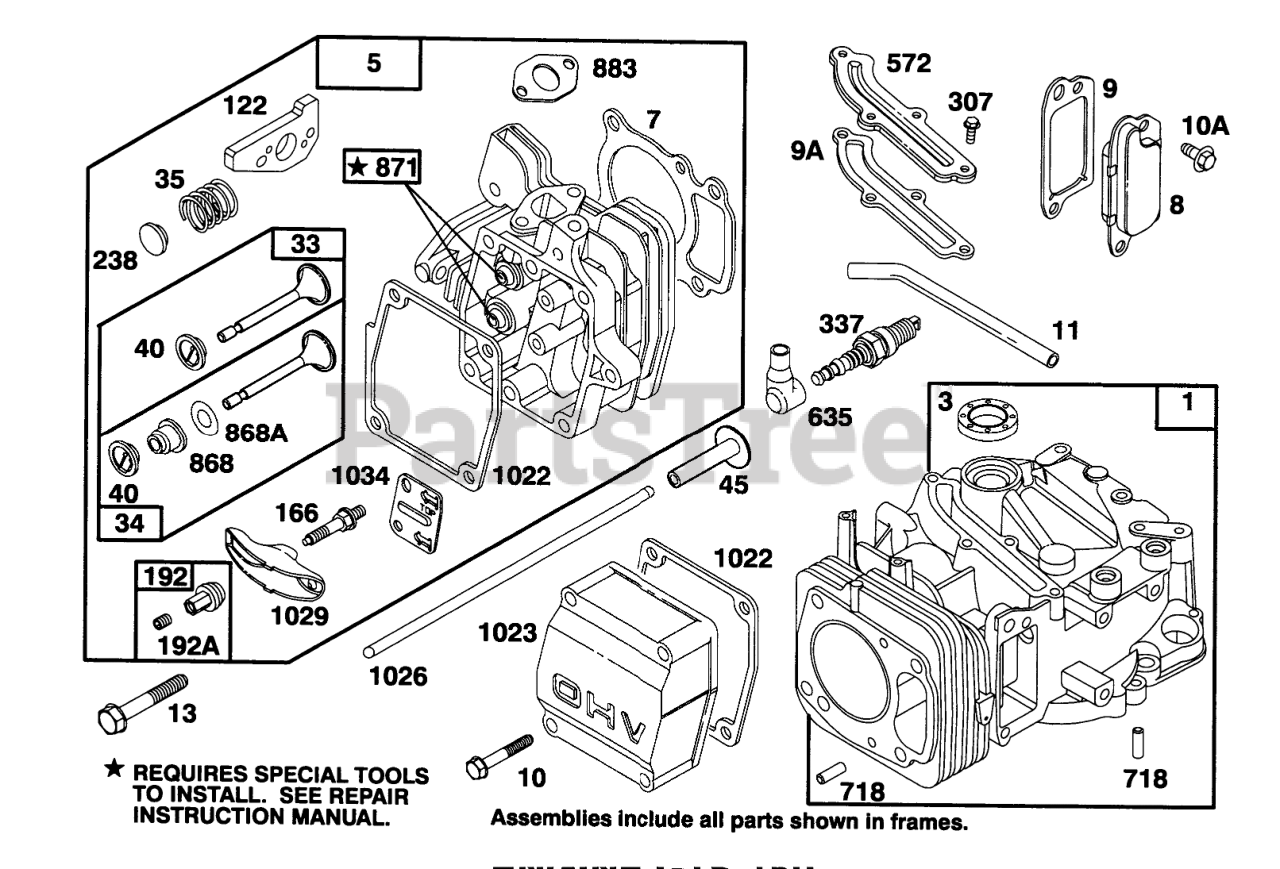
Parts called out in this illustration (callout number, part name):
1	CYLINDER ASSEMBLY
3	SEAL - OIL
5	CYLINDER HEAD
7	CYLINDER HEAD GASKET
8	BREATHER ASM
8	BREATHER GASKET
9	BREATHER GASKET
9A	GASKET-BREATHER
10	HEX HEAD SCREW
10A	HEX HEAD SCREW
11	BREATHER TUBE
13	CYLINDER HEAD SCREW
33	EXHAUST VALVE
34	INTAKE VALVE
35	VALVE SPRING
40	SPRING RETAINER
45	VALVE TAPPET
116	O-Ring
122	ADAPTER ASSEMBLY
166	ROCKER ARM STUD
192	NUT - HEX SPECIAL
192A	Screw-Set
238	VALVE CAP
307	SCREW - SEM
337	PLUG-SPARK
572	BAFFLE - CYCLINDER
635	SPARK PLUG ELBOW
718	DOWEL - SLEEVE
868	SealAssy-Valve
868A	Seal-Valve
871	Bushing-Guide
883	EXHAUST GASKET
1022	ROCKER COVER GASKET
1023	Cover-Valve
1026	PUSH ROD
1029	ROCKER ARM
1034	PUSH ROD GUIDE
